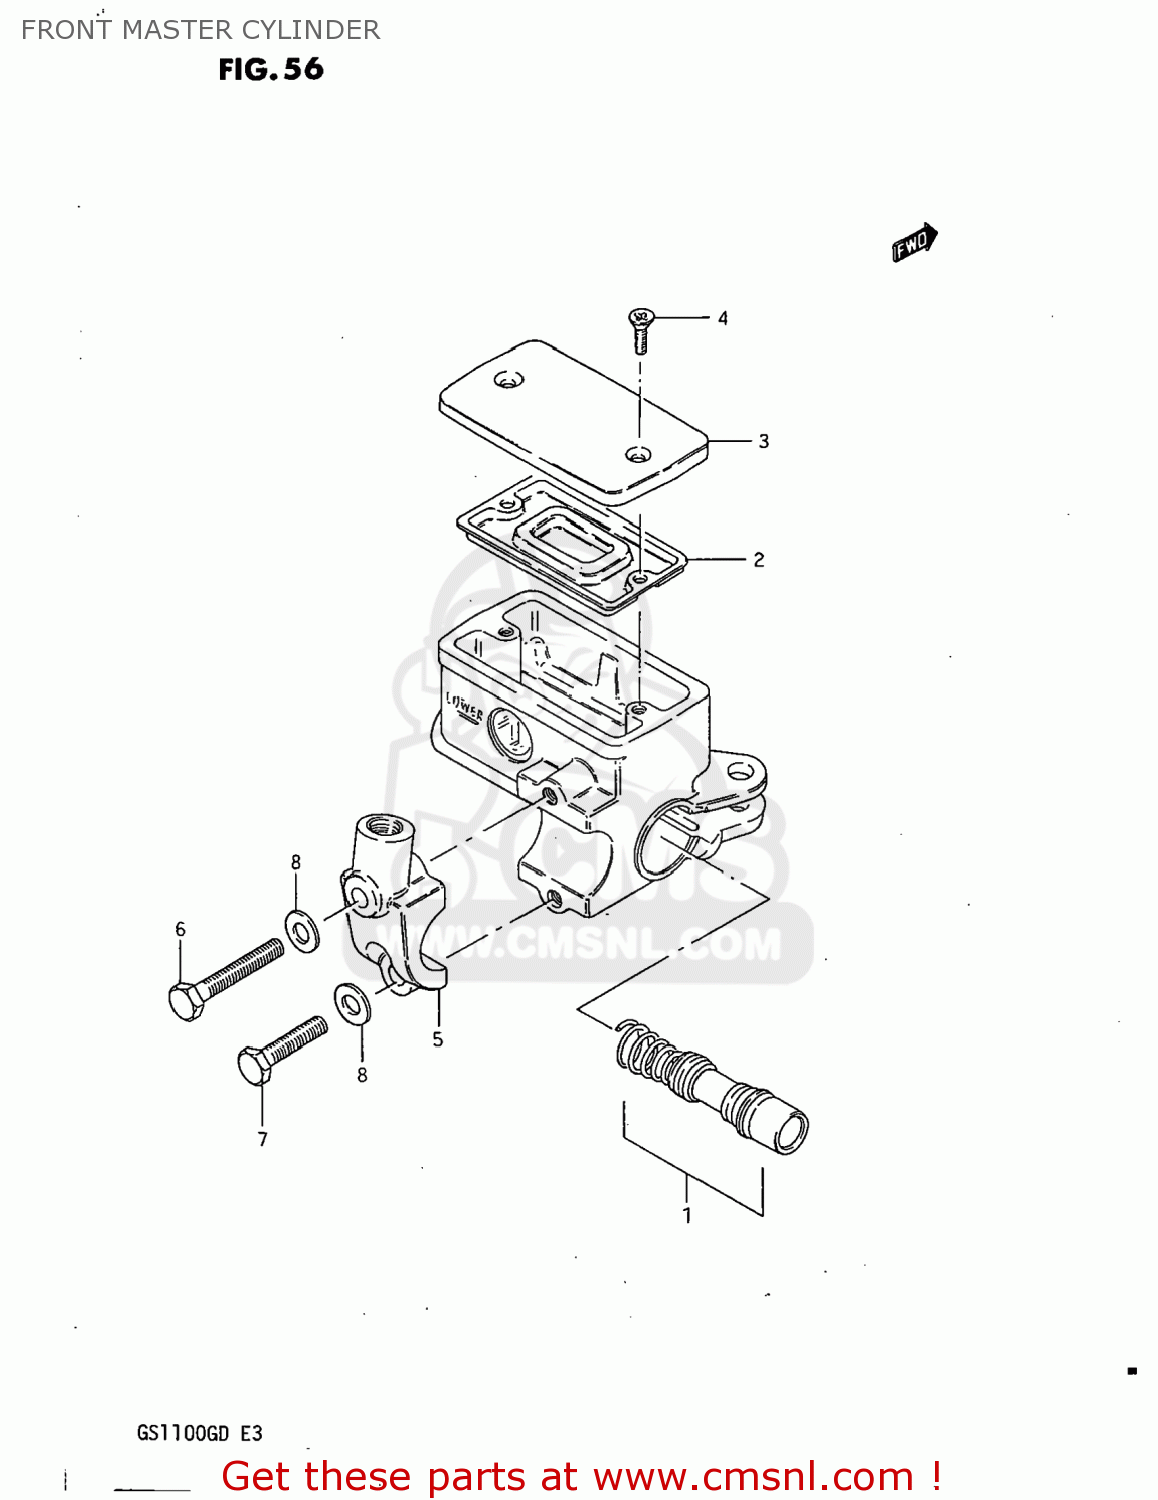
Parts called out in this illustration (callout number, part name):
1	PISTON & CUP SET
2	3
3	CAP
4	SCREW
5	HOLDER
6	BOLT 6X40
7	BOLT
8	WASHER
